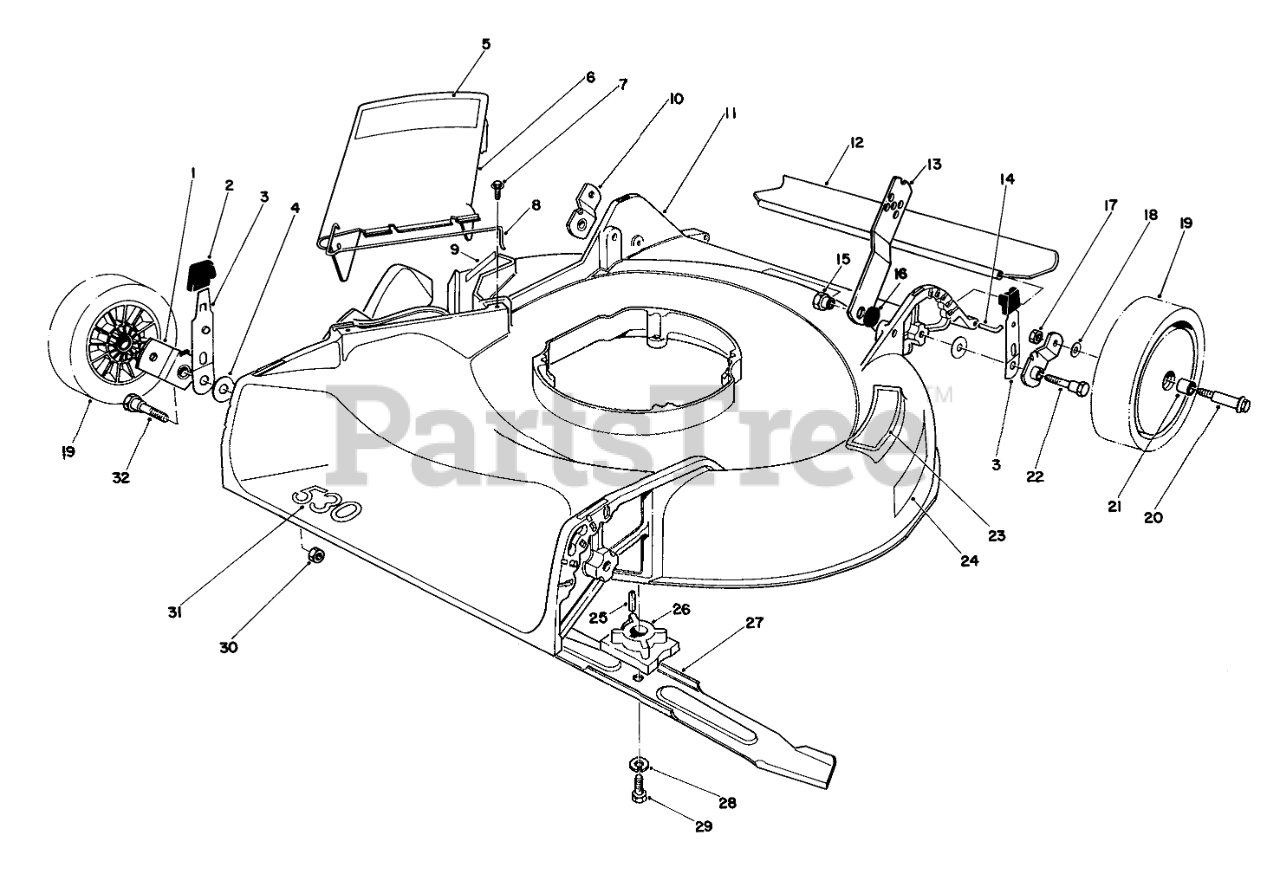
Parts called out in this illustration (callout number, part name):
1	Pivot Arm
2	KNOB-ARM
3	SPRING ARM ASM
4	WASHER-PIVOT
5	Decal-Danger(French)
6	Deflector Assy. (Incl. Ref. #5&8)
7	SCREW-HWH
8	SPRING HINGE
9	Decal-Danger
10	Pivot Arm
11	HOUSING/DECAL
12	REAR SAFETY SHIELD 21
13	Handle Latch
14	SHIELD ROD
15	HANDLE PIVOT NUT
16	HANDLE LATCH SPACER
17	Nut
18	WASHER
19	Wheel & Tire Assembly (Incl. Ref. #21)
20	BOLT-WHEEL
21	BUSHING
22	PIVOT SCREW
23	STEP PAD DECAL
24	Decal-Step
25	KEY-SQUARE
26	Blade Retainer
27	Blade
28	WASHER-LOCK
29	SCREW-HH
30	NUT-LOCK, NI
31	Decal-530
32	PIVOT SCREW
